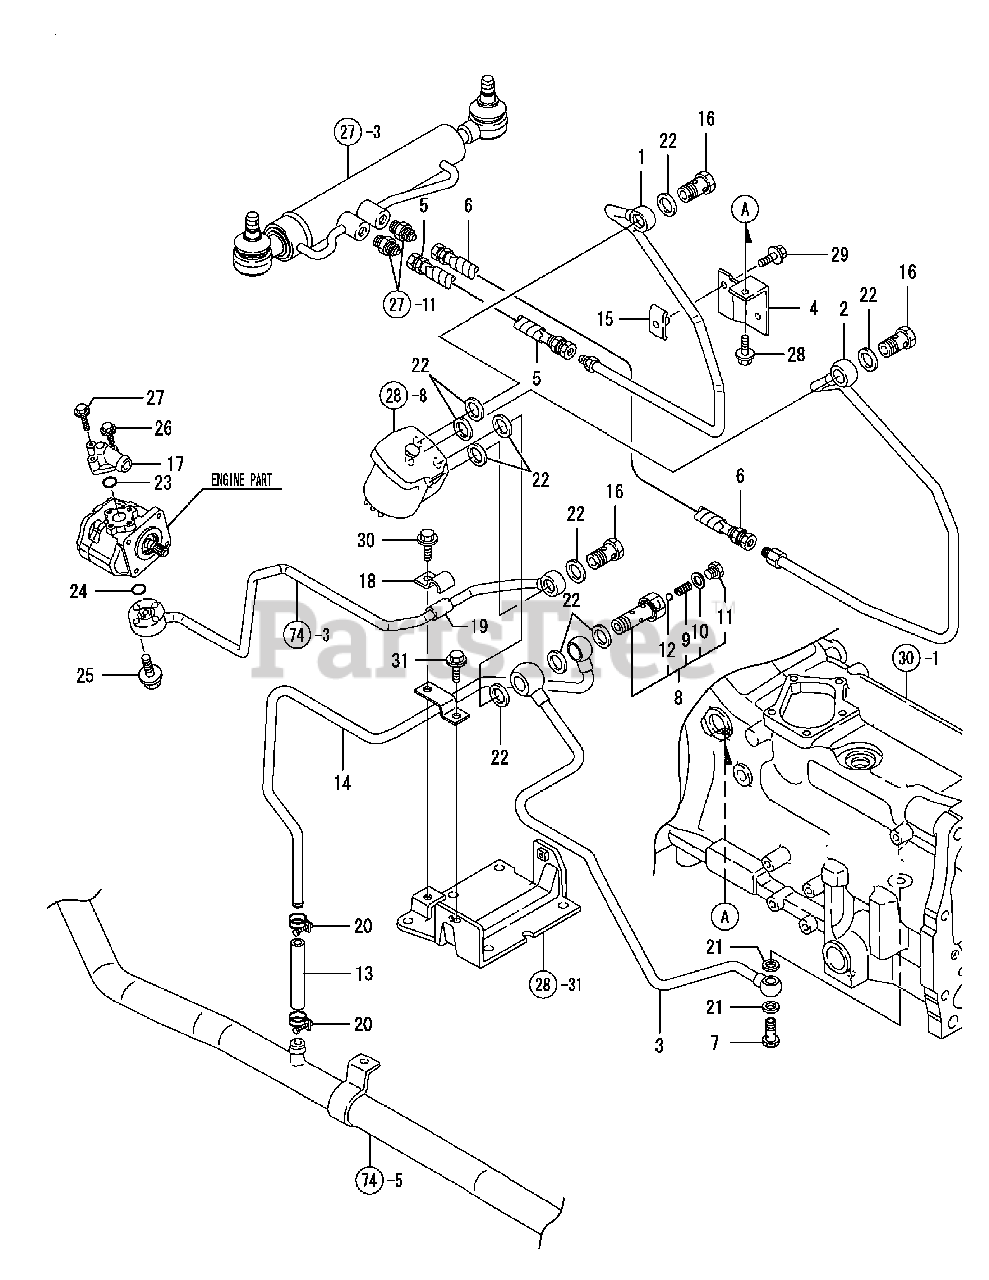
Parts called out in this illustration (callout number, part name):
1	PIPE, PST L.H.
2	LINE,PRESSURE RH
3	PIPE,SYNCHRO(PST T
8	BOLT,JOINT 3/4-16CMP
9	SPRING, CHECK VALVE
10	GASKET 12, ROUND
12	BALL 5/16, STEEL
14	PST LINE, SUCTION
21	GASKET 12, ROUND
23	O-RING 1A P-20.0
24	O-RING 1A P-20.0
26	BOLT M 6X 20 PLATED
27	BOLT M 6X 40 PLATED
28	BOLT M 8X 16 PLATED
29	BOLT M 8X 20 PLATED
30	BOLT M 8X 20 PLATED
31	BOLT M 8X 20 PLATED
